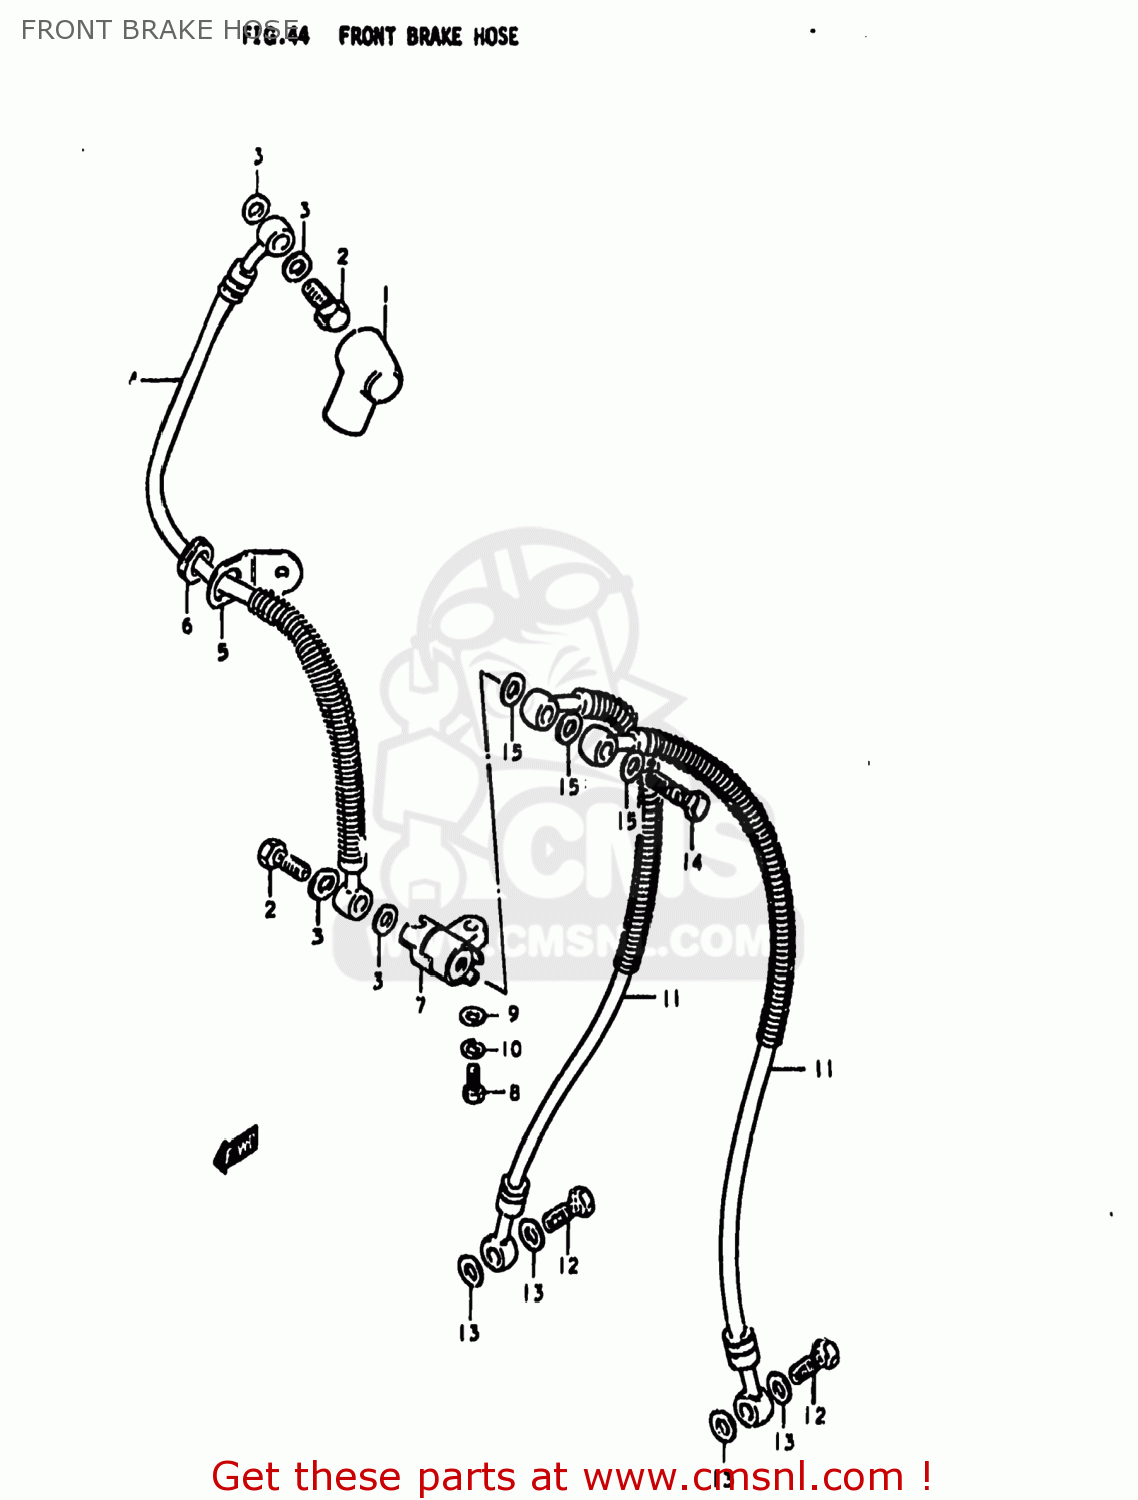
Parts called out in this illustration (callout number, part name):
1	BOOT,MASTER CYLINDER
2	BOLT UNION
3	WASHER
4	HOSE,FRONT BRAKE
5	GUIDE,BRAKE HOSE
6	GROMMET
7	JOINT,BRAKE HOSE
8	BOLT
9	WASHER
10	LOCK WASHER
11	HOSE,FRONT BRAKE
12	BOLT UNION
13	WASHER
14	BOLT UNION
15	WASHER
